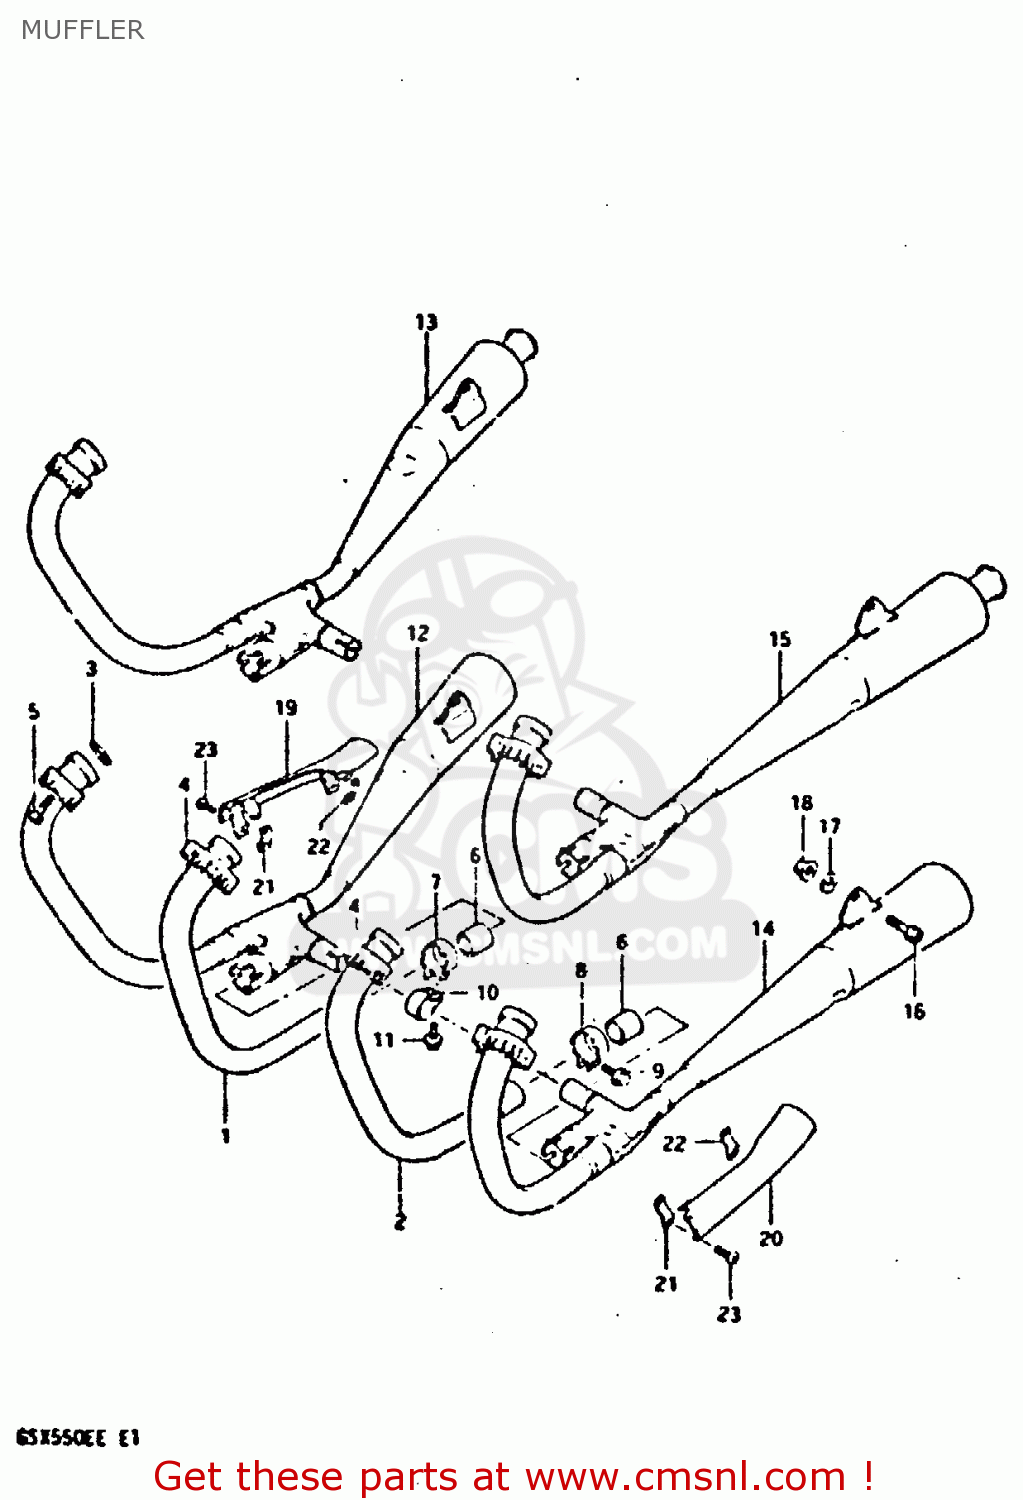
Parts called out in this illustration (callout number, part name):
1	PIPE,EXHAUST,CENTER,RIGHT
2	PIPE,EXHAUST,CENTER,LEFT
3	GASKET,EXHAUST PIPE (NAS)
4	CLAMP,EXHAUST PIPE
5	BOLT
6	CONNECTOR,MUFFLER
7	CLAMP,MUFFLER CONNECTOR
8	CLAMP,MUFFLER CONNECTOR
9	BOLT
10	CLAMP,EXHAUST
11	BOLT
12	MUFFLER, RH
14	MUFFLER, LH
16	BOLT
17	WASHER(10.5X20X3.2)
18	NUT
19	COVER,MUFFLER
20	COVER,MUFFLER
21	CLAMP,MUFFLER COVER
22	CLAMP,MUFFLER COVER
23	SCREW
